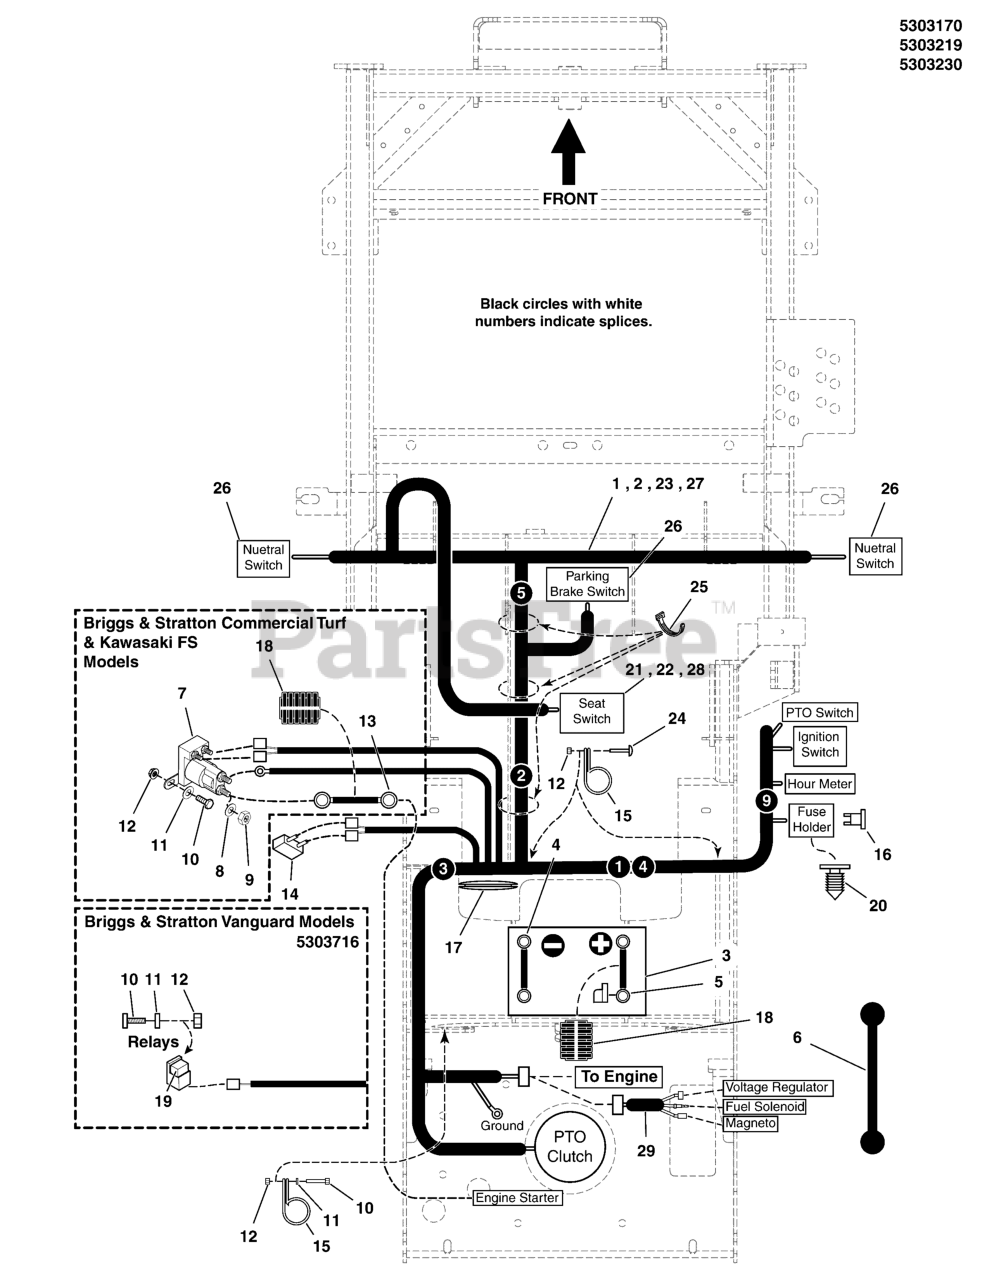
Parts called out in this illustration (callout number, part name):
1	WIRE HARNESS, C TURF,WARNER, IS600/IS700
3	BATTERY, WET ( BCIU1, 340 CCA)
4	BATTERY CABLE, NEG, 14, 5/16-13/32
5	BATTERY CABLE, POS, 22, 1/4-5/16
6	STRAP, BATTERY, 14 LONG, Rubber
7	SOLENOID-4 POLE 12 VOLT DC (TROMBETTA)
8	WASHER, Light Lock, 5/16
9	NUT, Hex Jam, 5/16-24
10	BOLT, 1/4"-20 X 3/4" GD5 YZ
11	WASHER, 1/4 SAE
12	NUT, 1/4-20 HEX SERR. FLANGE
13	BATTERY CABLE, POS, 22, 1/4-5/16
14	BREAKER-CIRCUIT 12VOLT 20AMPS W/TAB
15	CLAMP, VINYL INSULATED, 1.00
16	FUSE, ATO-15 (15 AMP)(SV)
17	GROMMET, 1-1/2" ID FOR 1/4" METAL
18	WIRE LOOM, 3/8 ID X 18 IN
19	RELAY, 12 VOLT, 40 AMP
20	FIR TREE MOUNT, PACKARD
21	SWITCH, NC, W/ BOLT-IN BASE
22	SWITCH, NC, W/ TWIST-IN BASE
23	WIRE HARNESS, VAN GRD, WARNER, IS600/700
24	SCREW, 1/4-20 X 1, ALLEN BH, CZ
25	TIE, SELF-LOCKING, 6"
26	SWITCH, DP NO/NC SNAP-IN
27	WIRE HARNESS, M49 VANGUARD, WARNER, 700
28	DELTA SWITCH - NORMALLY CLOSED
29	WIRE HARNESS, JUMPER, KAWI
